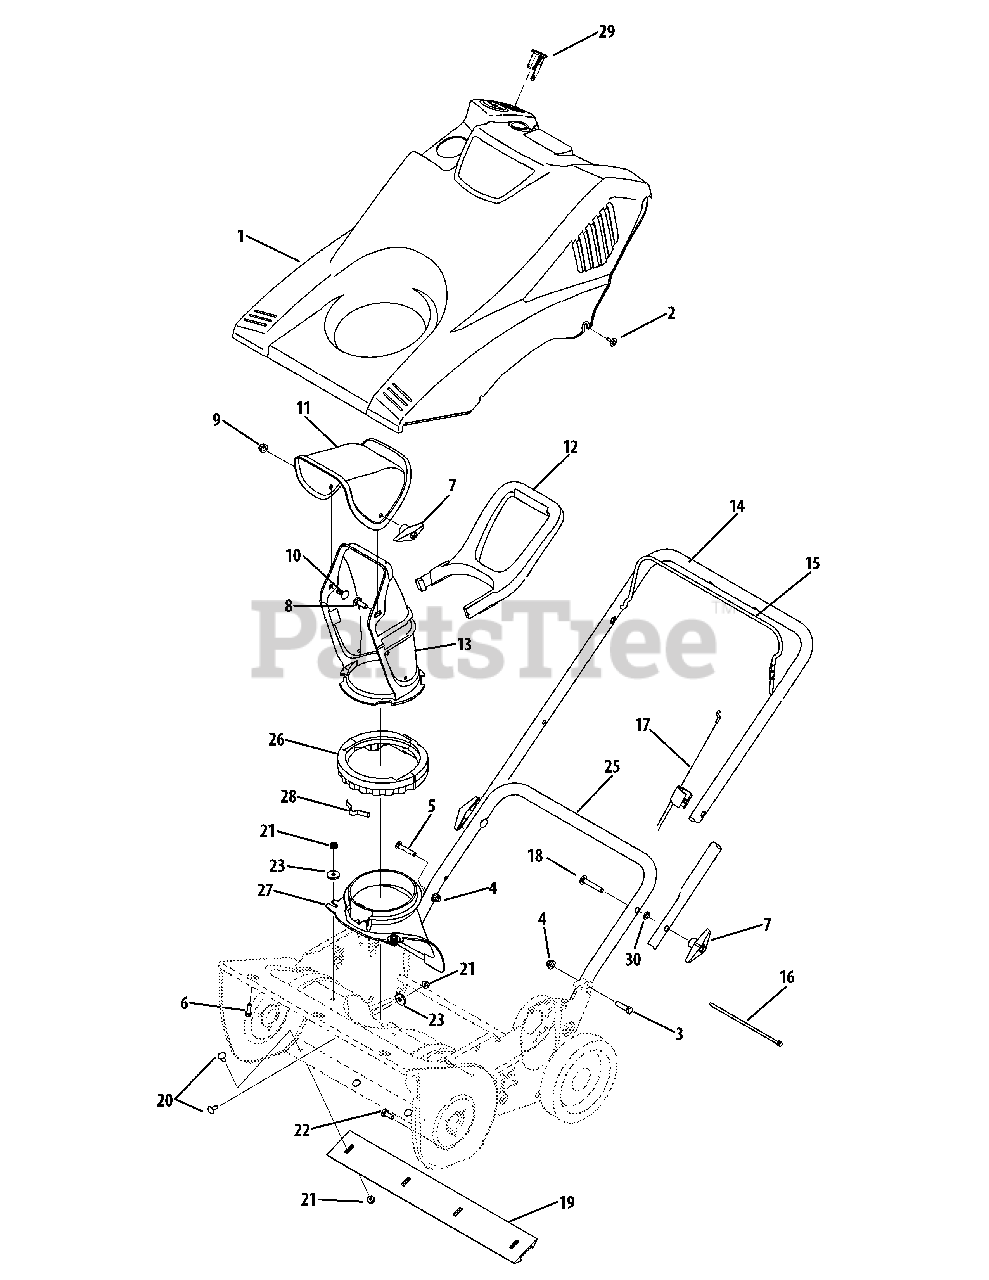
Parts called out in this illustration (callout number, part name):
1	Shroud
2	Hex Wash B-Tapp Scr #10-16 x .62" Lg.
3	Hex Scr. .312-18 x 1.250
4	Flange Locknut 5/16-18 Gr. F, Nylon
5	Hex Scr. 5/16-18 x 1.50 Gr. 5
6	Hex Tapp Scr 1/4 x .75" Lg.
7	Handle Knob Assembly
8	Carriage Screw 5/16-18 x 1.0
9	Flange Locknut 5/16-18 Gr. F, Nylon
10	Carriage Bolt 5/16-18 x .75
11	Upper Chute
12	Chute Handle
13	Lower Chute 5" Dia
14	Upper Handle
15	Bail Control
16	Cable Tie
17	Control Cable
18	Carriage Bolt 5/16-18 x 2.0
19	Shave Plate
20	Carriage Bolt 1/4-20 x .62
21	Hex L-Flanged Nut 1/4-20 Gr. F Nylon
22	Hex Bolt 5/16-18 x .75" Lg. Gr. 5
23	Flat Washer .25 ID x .93 OD x .125
24	Spacer .875 x .320 x 1.027
25	Lower Handle
26	Ring-Lower Chute
27	Chute Adapter 5" Dia
28	Chute Adjustment Spring
29	Ignition Switch
30	Speed Nut
